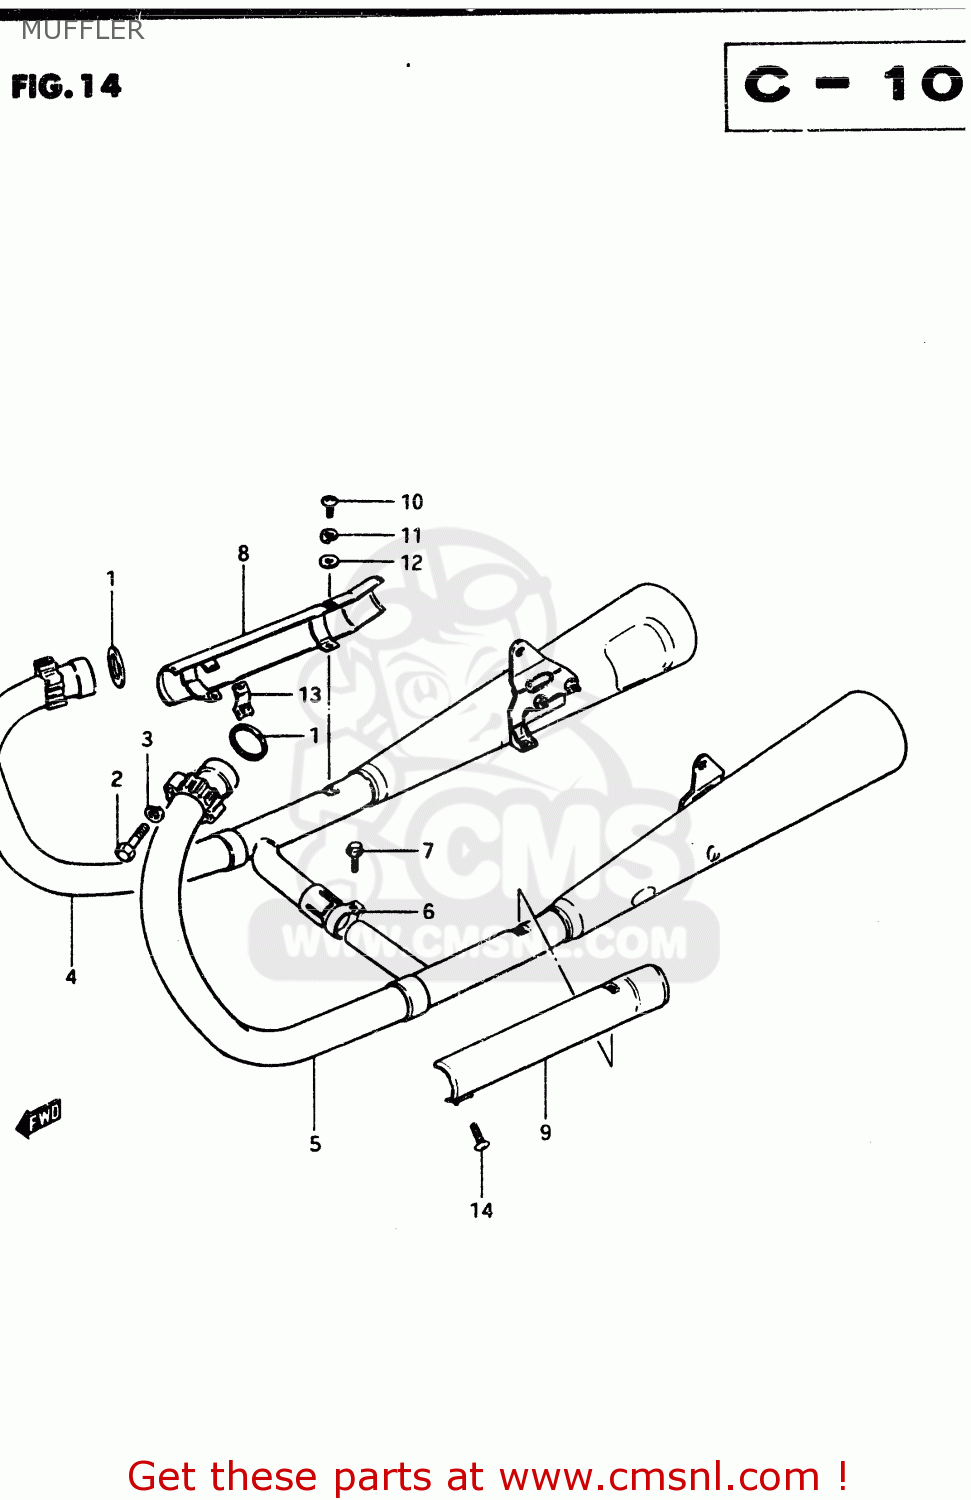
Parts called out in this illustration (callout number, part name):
1	GASKET,EXHAUST PIPE (NAS)
2	BOLT 8X40
3	LOCK WASHER
4	MUFFLER ASSEMBLY
5	MUFFLER ASSEMBLY
6	CLAMP
7	BOLT
8	COVER,MUFFLER,RIGHT
9	COVER,MUFFLER LH
10	SCREW
11	LOCK WASHER
12	WASHER
13	CLAMP,MUFFLER COVER
14	SCREW
